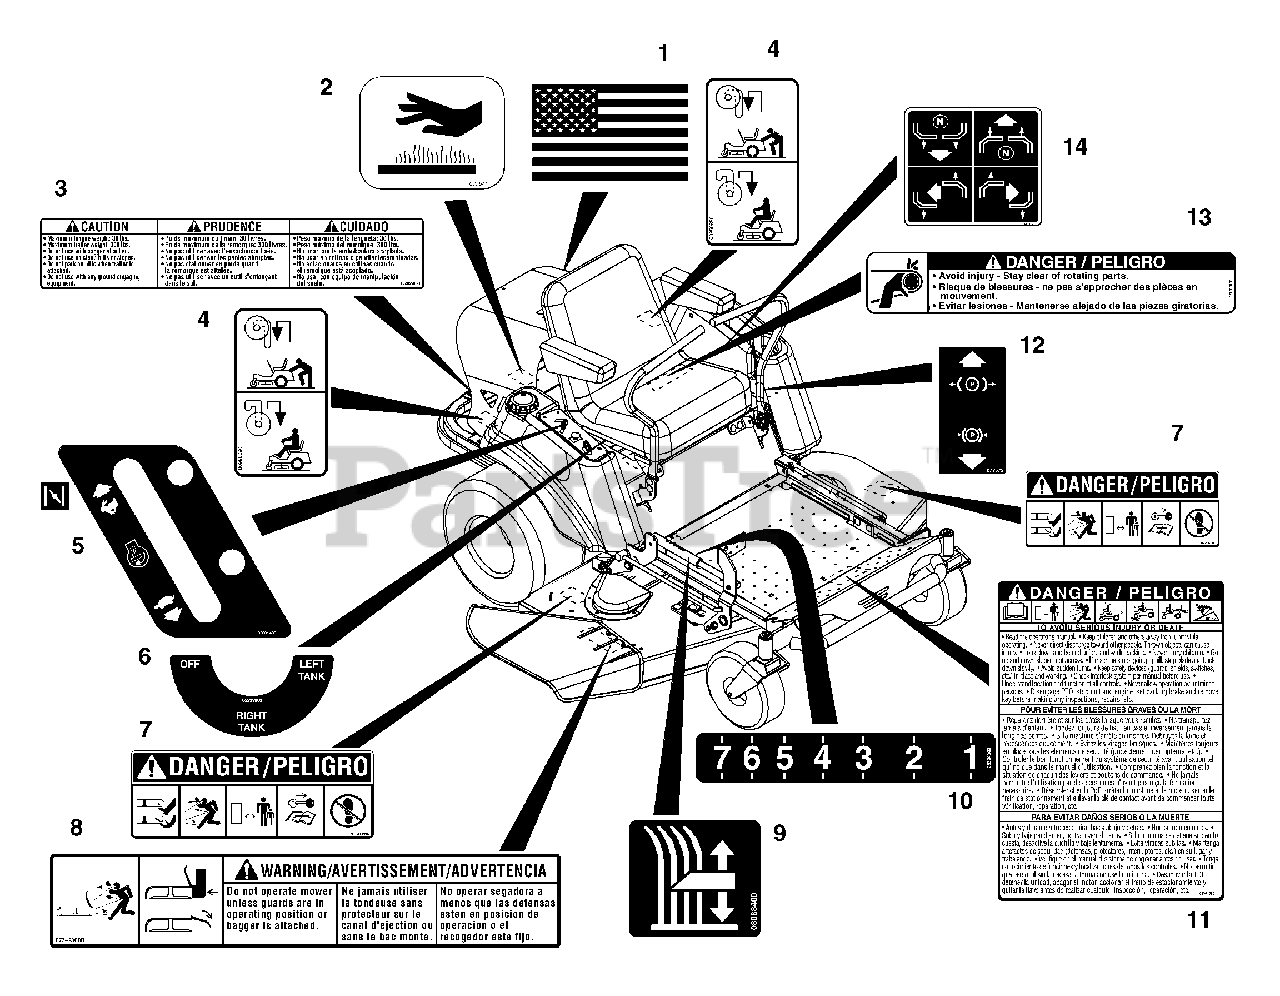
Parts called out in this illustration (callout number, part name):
1	DECAL, AMERICAN FLAG
2	DECAL, HOT SURFACE
3	DECAL, TRAILER HITCH
4	DECAL, TRANSMISSION DISCONNECT
5	DECAL, SPEED CONTROL
6	DECAL, FUEL VALVE
7	DECAL, MOWER PAN DANGER
8	DECAL, WARNING
9	DECAL-CUT HEIGHT
10	DECAL CUT HEIGHT
11	DECAL, DANGER BILINGUAL
12	DECAL, PARKING BRAKE LEVER
13	DECAL- DANGER
14	DECAL, INSTRUCTIONAL-STEERING
